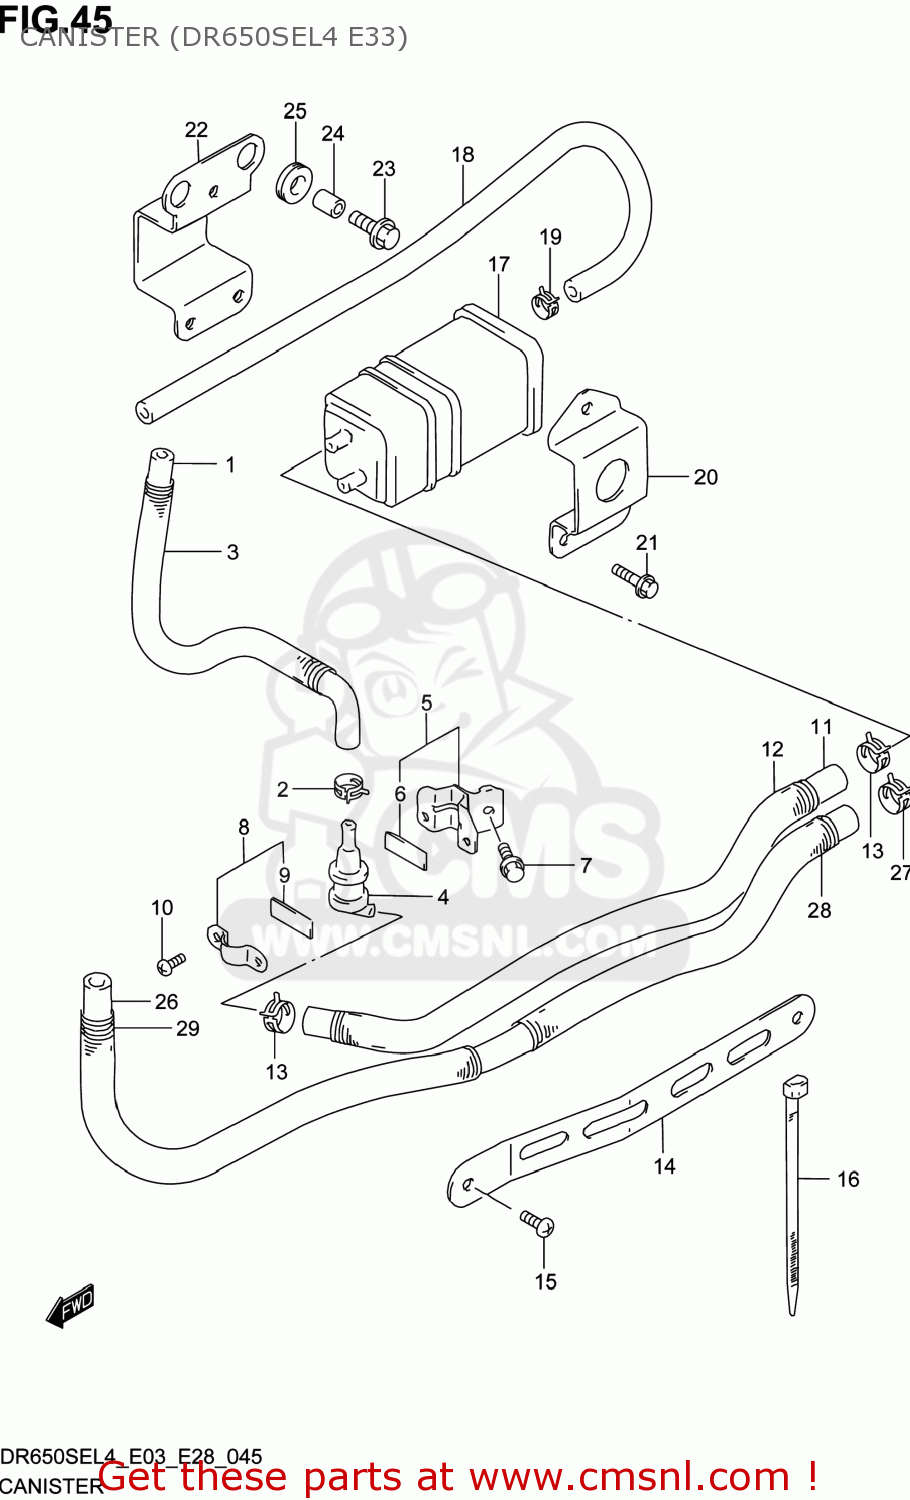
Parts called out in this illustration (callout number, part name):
1	HOSE,TANK & VALVE CHARGE
2	CLIP
3	SPRING
4	VALVE,FUEL TANK BREATHER
5	PLATE,BREATHER VALVE
6	CUSHION
7	BOLT
8	PLATE,FUEL TANK BREATHER NO.2
9	CUSHION
10	SCREW
11	HOSE,VALVE & CANISTER CHARGE
12	SPRING
13	CLIP
14	PLATE,CANISTER HOSE
15	SCREW
16	CLAMP(L:125)
17	CANISTER ASSY,CHARCOAL
18	HOSE(7X12X600)
19	CLIP
20	PLATE,CSTR UPR
21	BOLT
22	PLATE,CSTR LWR
23	BOLT(6X20)
24	SPACER(6.5X10X9.4)
25	CUSHION
26	HOSE,CSTR & CARB PURGE
27	CLIP
28	SPRING
29	SPRING
